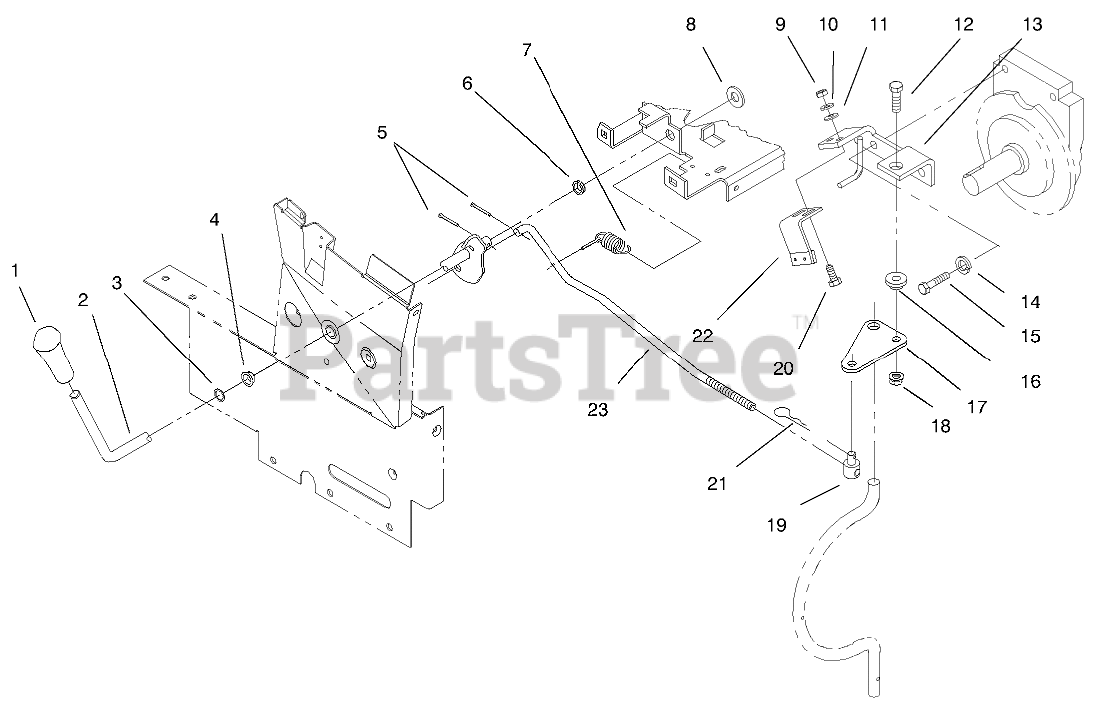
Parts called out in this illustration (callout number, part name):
2	PTO CLUTCH LEVER ASM
3	RING-EXT GRIP
4	BUSHING-NYLINER
5	PIN-COTTER
7	SPRING
8	SHIM-WASHER
9	NUT-JAM
10	WASHER-LOCK
11	WASHER-FLAT
12	SCREW-HH
13	BRCKET-ENGINE (BLACK)
14	WASHER-LOCK
15	SCREW-HH
16	SPACER-LIFT LINK
17	PLATE
18	NUT-LOCK, NI
19	TRUNNION
20	SCREW-CARR
21	PIN-HAIR
22	BRAKE ASM
23	ROD-PTO CLUTCH
